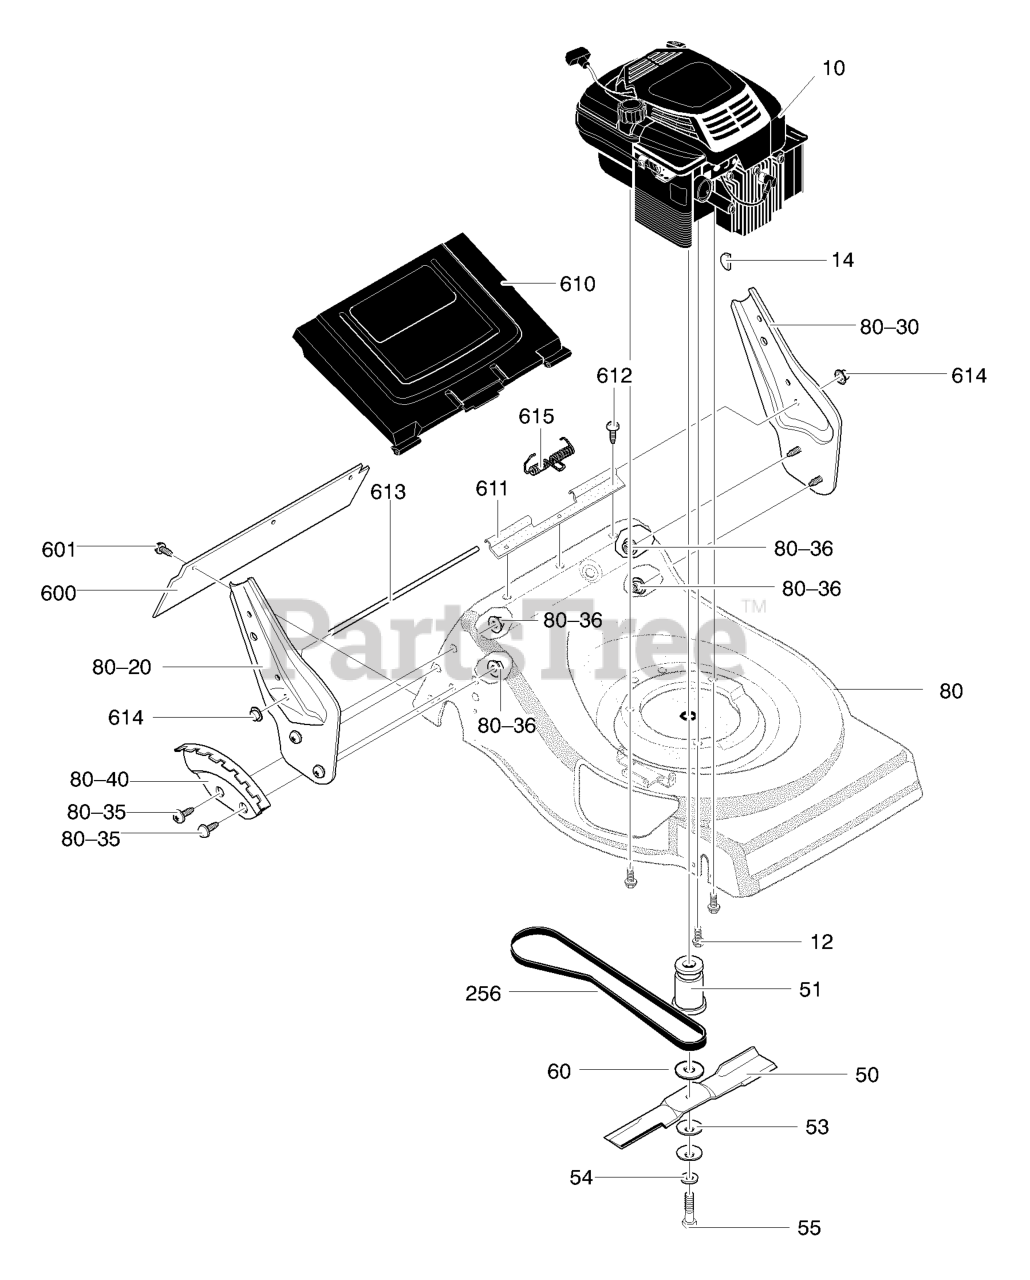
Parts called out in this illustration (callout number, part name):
10	ENGINE
14	WOODRUFF KEY
51	ADAPTER, BLADE
53	WASHER
80	ASSY, FRAME
80-20	BRKT., HANDLE RH
80-30	BRKT., HANDLE LH
80-40	INDEX, HEIGHT ADJ
256	BELT, V
600	DEFLECTOR, REAR
610	DOOR, REAR 21
613	ROD, PIVOT
614	CAP, PUSH ON
615	SPRING, TORSION
